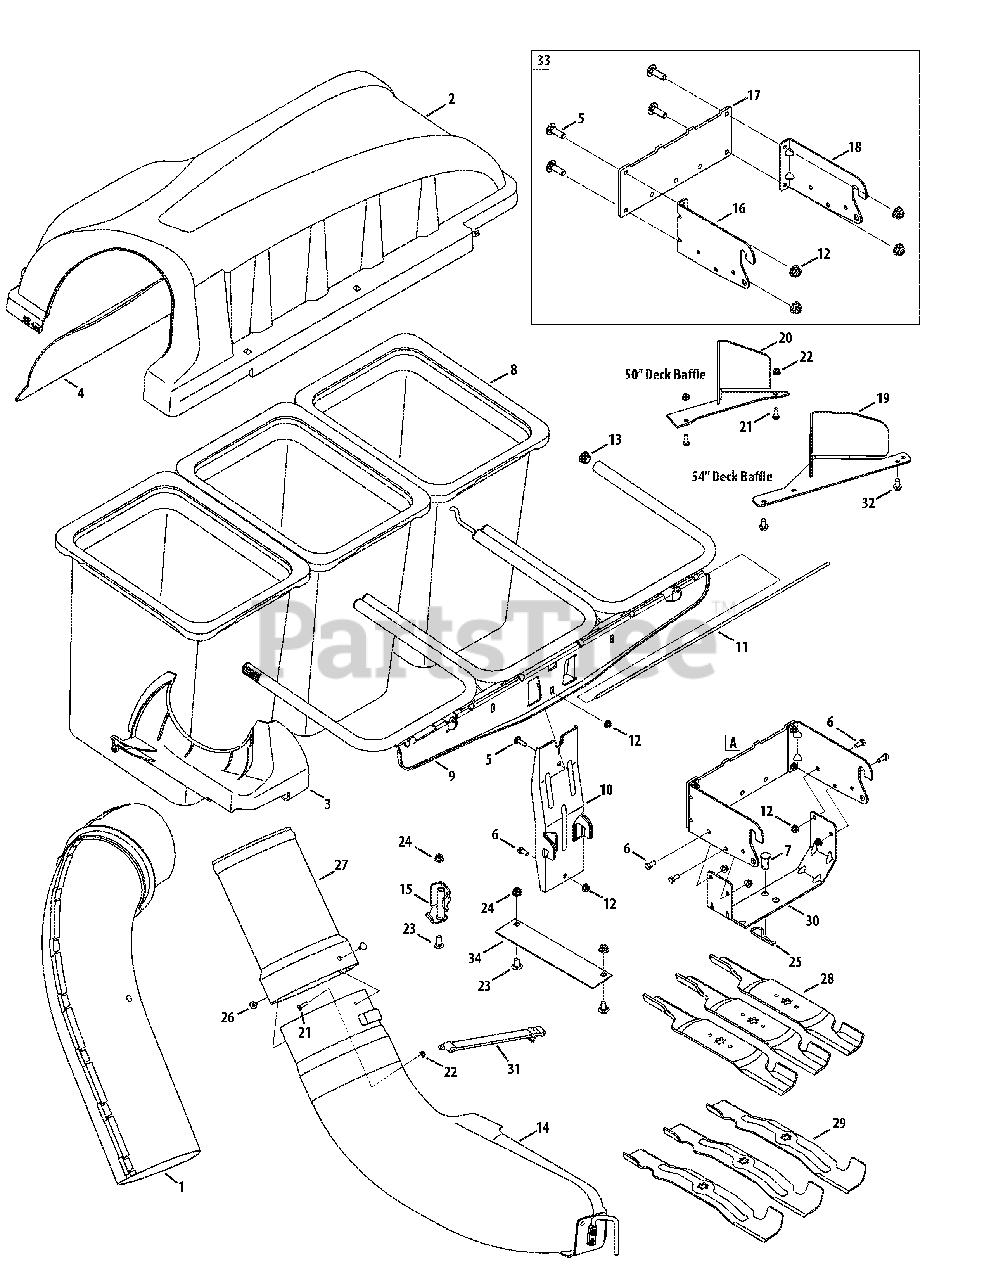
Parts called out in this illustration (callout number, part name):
1	Upper Chute Assembly
2	Triple Bagger Cover Assembly
3	Upper Chute Support
4	Bagger Cover Screen
5	Carriage Screw, 5/16-18 x 1.00"
6	Hex Head Screw, 5/16-18 x .75"
7	Clevis Pin, .62" Dia.
8	Grass-bag Assembly
11	Cover Hinge Pin
12	Flange Lock Nut, 5/16-18
14	Discharge Chute Elbow, 50/54" Deck
15	Chute Stop-Bracket
16	Hitch Bracket, RH
17	Universal Rear Attachment Bracket
18	Hitch Bracket, LH
19	Deck Baffle, 50"
20	Deck Baffle, 54"
21	Tap Screw, 1/4 - 20 x .750 (50" Deck)
21	Tap Screw, 5/16-18 x .750 (54" Deck)
22	Flange Lock Nut, 1/4 - 20 (50" Deck)
23	Carriage Screw, 3/8 - 16 x 1.00"
24	Flange Lock Nut, 3/8 - 16
25	Internal Cotter Pin, .148 x 3.00
26	Ratchet Clip, .250
27	Bagger Chute Adapter, 7 In.
28	Blade, 17.90 Lg., Star Bagging
29	Blade, 18.50 Lg., Star Bagging
30	Universal Bracket Support, RT-99/LT-5
31	Chute Strap
32	Tap Screw, 5/16-18 x .750 (54" Deck)
33	Mounting Bracket Kit (Incl. Ref. 16-18)
34	Discharge Chute Plate
